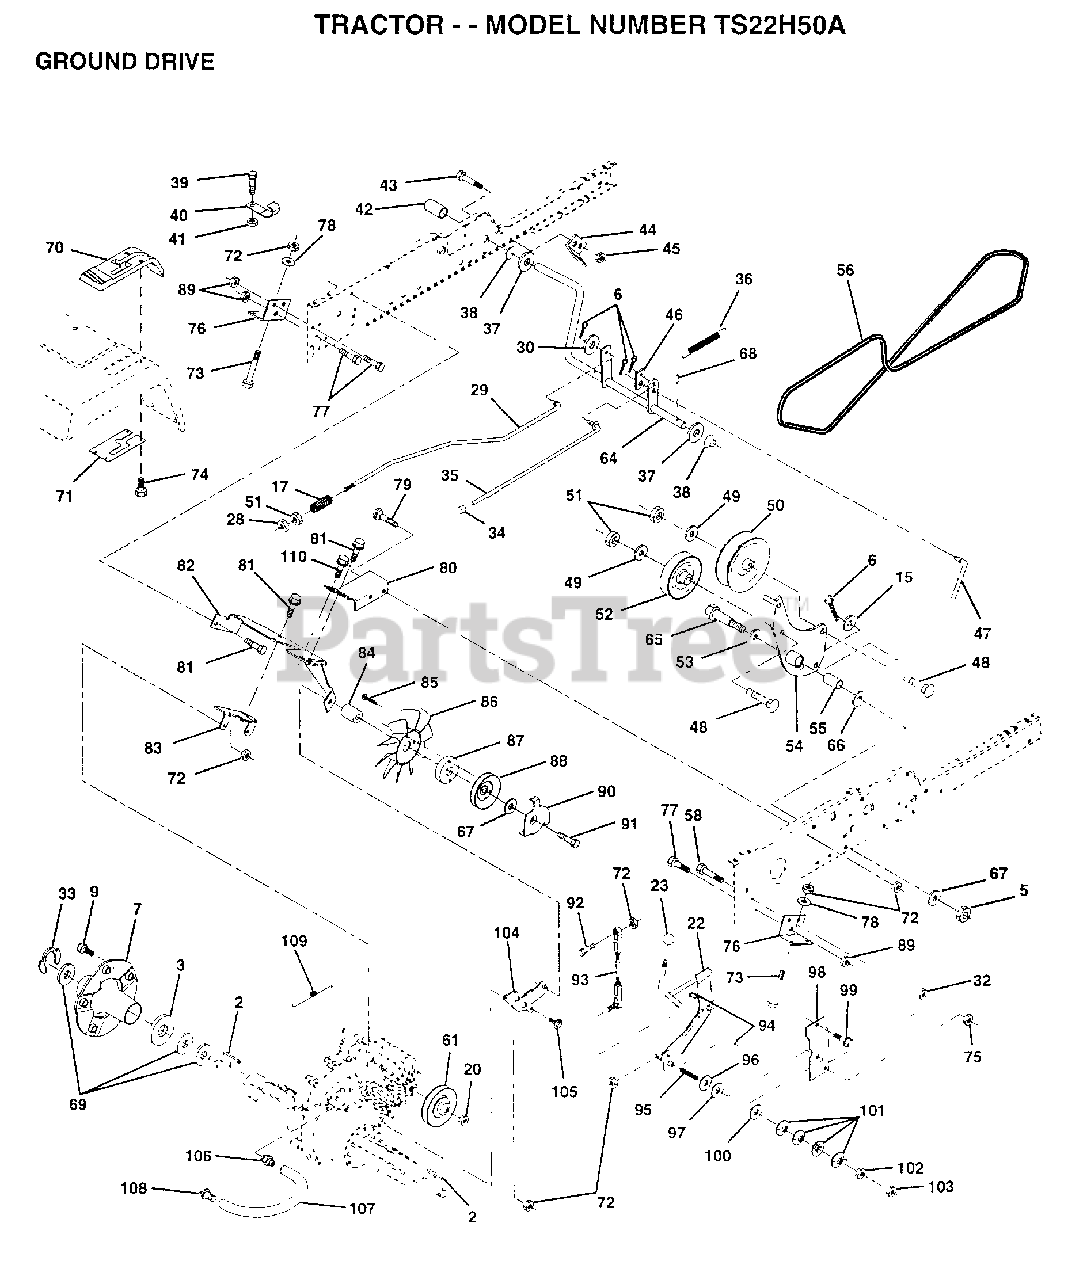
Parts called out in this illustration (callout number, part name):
2	KEY 1/4 X 2.5
3	WASHER T
6	COTTER PIN
7	HUB WHEEL ASM
9	BOLT.HUB.WHL.REAR
15	WASHER
17	SPRING ROD BRAKE
22	SHAFT ARM ASM
23	KNOB.DUCKHEAD.1/2
28	NUT
29	ROD BRAKE
30	WASHER HYT
32	NUT
33	E RING HYT
34	PLUNGER CAP T
35	ROD BRAKE PART GT
36	SPRING.GRND.DRIVE
37	WASHER
38	BUSHING.NYLINER
39	SCREW
40	ACT-SWITCH T
42	PEDAL COVER T
43	BOLT LT
44	BRKT SWITCH GT
45	NUT
46	RETAINER.SPRING
47	ROD.CLUTCH
48	BOLT
49	WASHER
50	FLAT IDLER PULLEY
51	NUT
52	PULLEY.IDLER.V.GR
53	WASHER T
54	ARM.ASM.IDLER.CLU
55	"LY, BEARING"
56	BELT-V 84.5
58	BOLT
61	PULLEY TRANSAXLE
65	AXLE BOLT
66	WASHER.HARD.BLADE
67	WASHER
68	ROLL PIN STD
69	WASHER
71	"PLATE CONSOLE,SFT"
72	NUT
73	BOLT FIN HEX 5/16
74	SCREW HEXWSH H-L
75	NUT.7/16
76	BRACKET TRAN VGTH
77	BOLT
78	WASHER
79	BOLT
80	BRACKET TORQUE RH
81	SCREW
82	BRACKET.MTG.FAN
83	STRAP TORQUE MID
84	SPACER
85	SCREW YTV
86	"FAN 7"" HYDRO"
87	ADAPTER FAN
89	NUT GTV
90	KEEPER BELT
91	SCREW.HXWSH.3/8
93	LINK ASM SHIFT
94	XMAS TREE FASTNER
95	SCREW SET 5/16
96	WASHER NICKEL PLT
97	BEARING THRUST
98	BRACKET SHIFT
99	SCREW LT
100	WASHER COMPRESSIN
101	WASHER
102	NUT HEX NYLOCK
103	JAM NUT TI
104	BRACKET IDLER
105	SCREW CRT
109	SPRING BRAKE
110	HINGE SCREW
